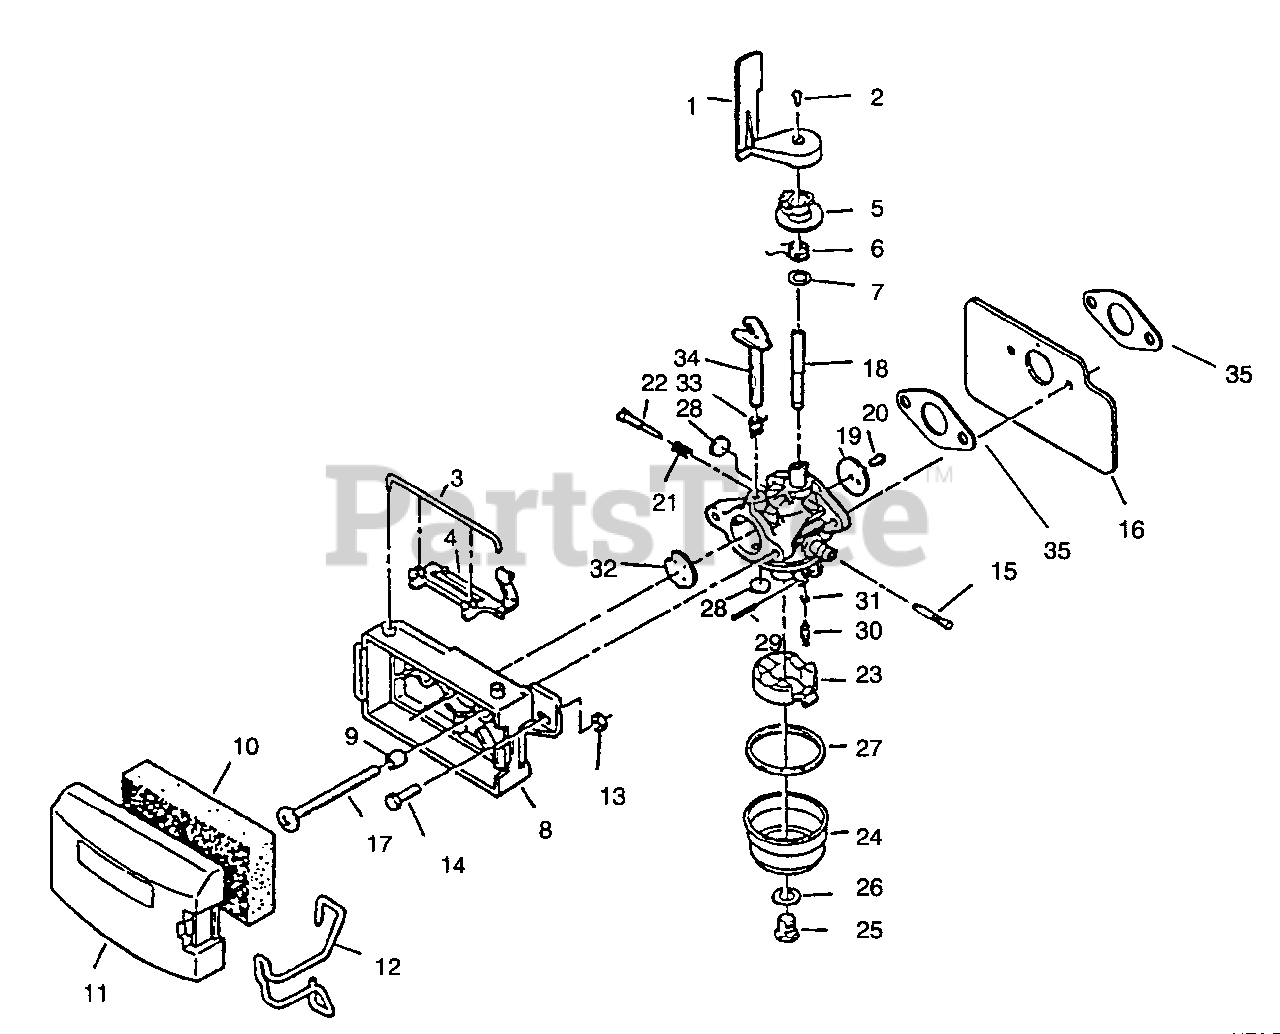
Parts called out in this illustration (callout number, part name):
1	Vane-Air
2	Screw
3	Retainer-Speed Control Lever
4	Lever-Governor Control
8	Base-Air Filter
9	Spacer-Filter Base
10	Element-Air Filter
11	Cover-Air Filter
12	Retainer-Cover
13	Nut
15	Filter-Fuel
16	Heat Shield
18	Shaft-Throttle
19	Vane-Throttle
20	Screw
21	Spring-Needle
22	Needle-Idle
23	Kit-Float Assembly
24	Bowl-Fuel
25	Screw
26	Gasket-Bowl Retainer
27	Gasket-Bowl
28	Plug-Welch
29	Shaft-Float
30	Inlet-Needle Valve
31	Seat-Valve
32	Valve-Choke
33	Spring-Return
34	Shaft-Choke
35	Gasket Carburetor
